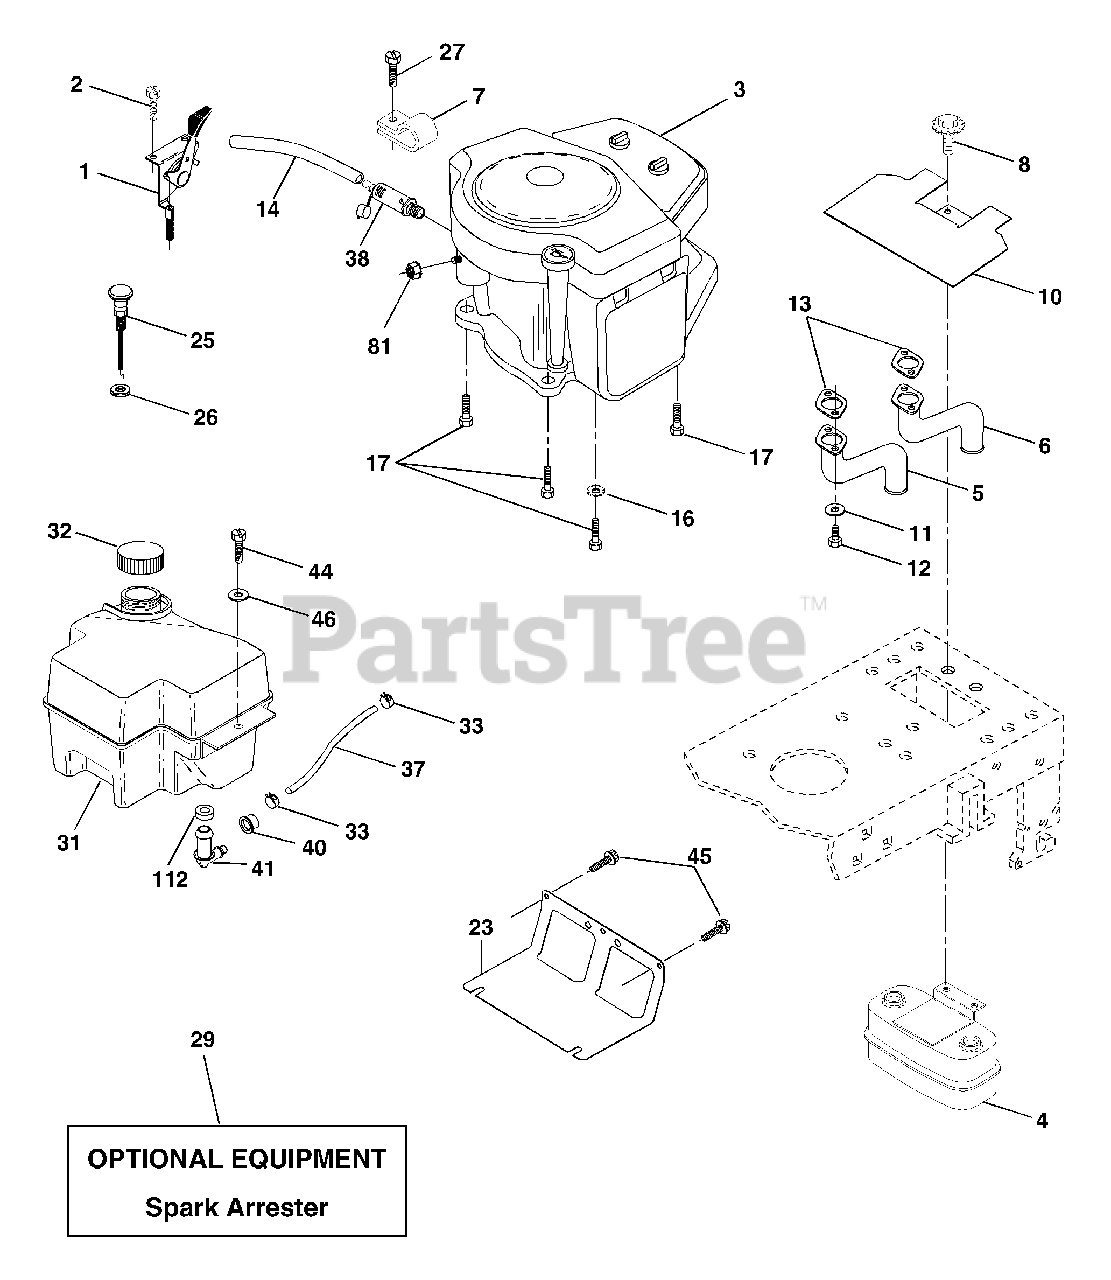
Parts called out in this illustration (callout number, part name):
1	Control Throt
2	Screw Hex Thd Cut 1/4-20x5/8 T
4	Muffler Exhaust
5	Exhaust Asm. Lh
6	Exhaust Asm. Rh
7	Clamp Tube Double Engine
8	Bolt 5/16-18unc x 3/4 w/sems
10	Heat Shield Lt
11	Washer Lock Hvy. Helical 1/4
12	Screw Hex Hd Cap 5/16-18 x 3/4
13	Gasket Muffler
14	Tube Drain Oil Easy
16	Washer Lock Ext Tooth 3/8
17	Screw 3/8-16x1-1/2
23	Shield BRN/DBR Guard
25	Control Choke
26	Nut Keps 3/8-24 Unf
27	Screw
29	Arrestor Spark
31	Tank Fuel
32	Cap Fuel
33	Clamp Hose Blk
37	Line Fuel
38	Plug Drain Oil Easy
40	Bushing Snap Nyl Black
41	Stem Tank Fuel
44	Screw Hexwsh Thdrol 1/4-20 x 3/4
45	Screw Hex wsh Thdrol 3/8-16 x 3/4
46	Washer 9/32 x 7/8 x 16 Ga.
81	Nut Keps Hex 1/4-20 Unc
112	Bushing
